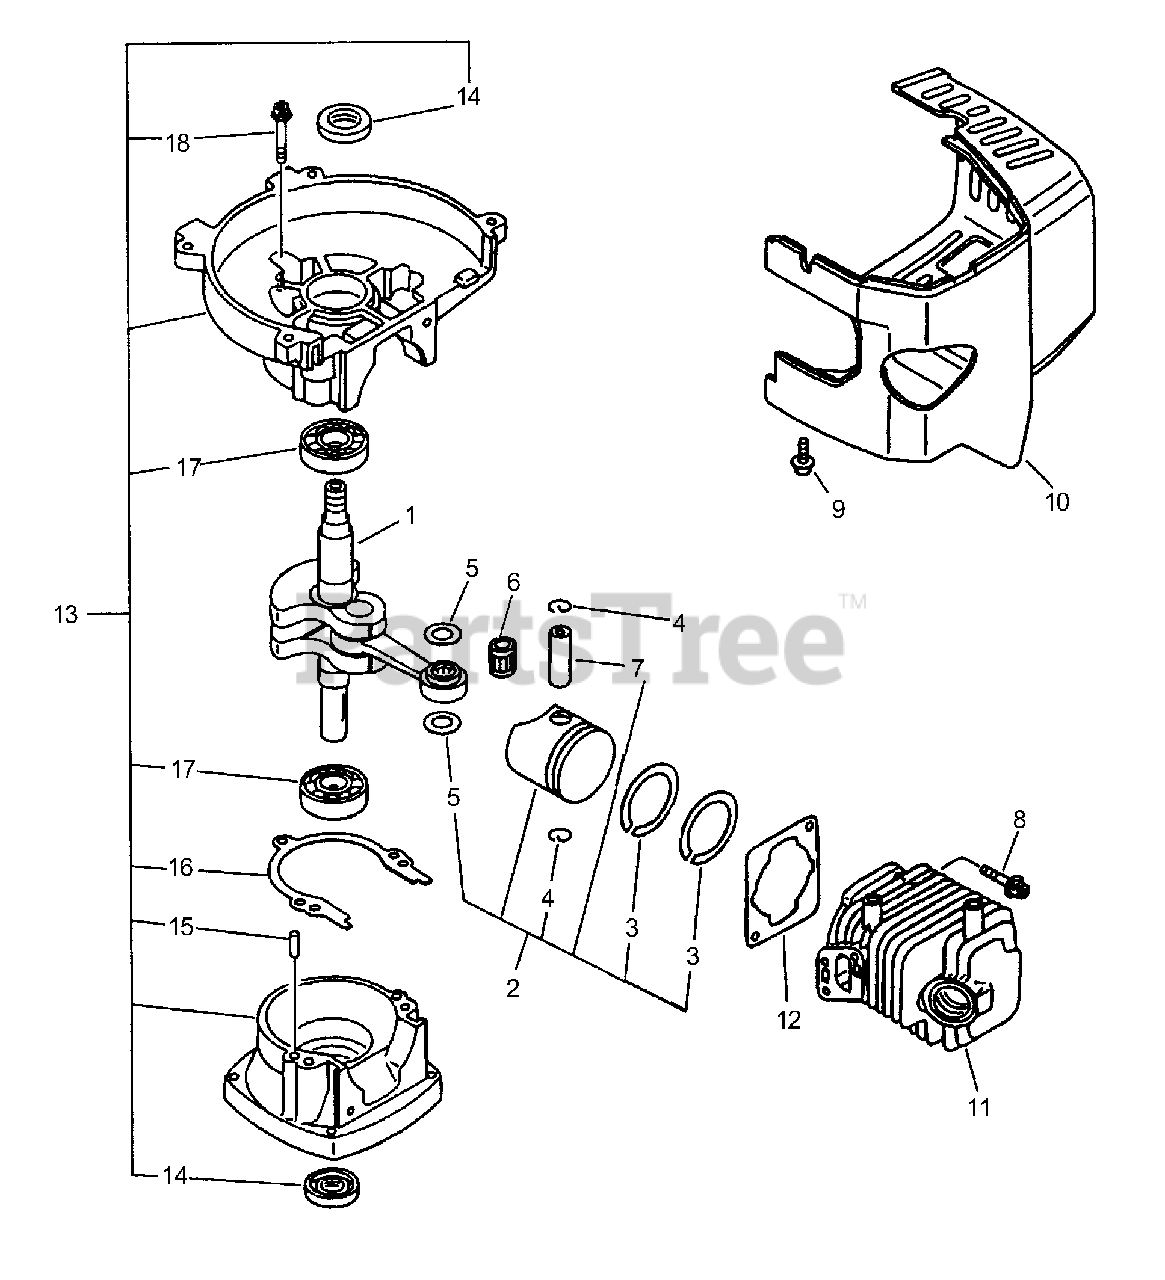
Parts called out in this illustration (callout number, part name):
1	CRANKSHAFT ASSY
2	PISTON KIT
3	RING, PISTON
4	RING, RETAINING
6	BEARING, NEEDLE - 8
7	PIN, PISTON
8	SCREW - 5X22
9	SCREW - 4X20
10	COVER, ENGINE
11	CYLINDER
12	GASKET, CYLINDER
13	CRANKCASE SET
14	SEAL, OIL
15	PIN - LOCATING
16	GASKET, CRANKCASE
17	BEARING, BALL - 6201
18	SCREW - 5X28
